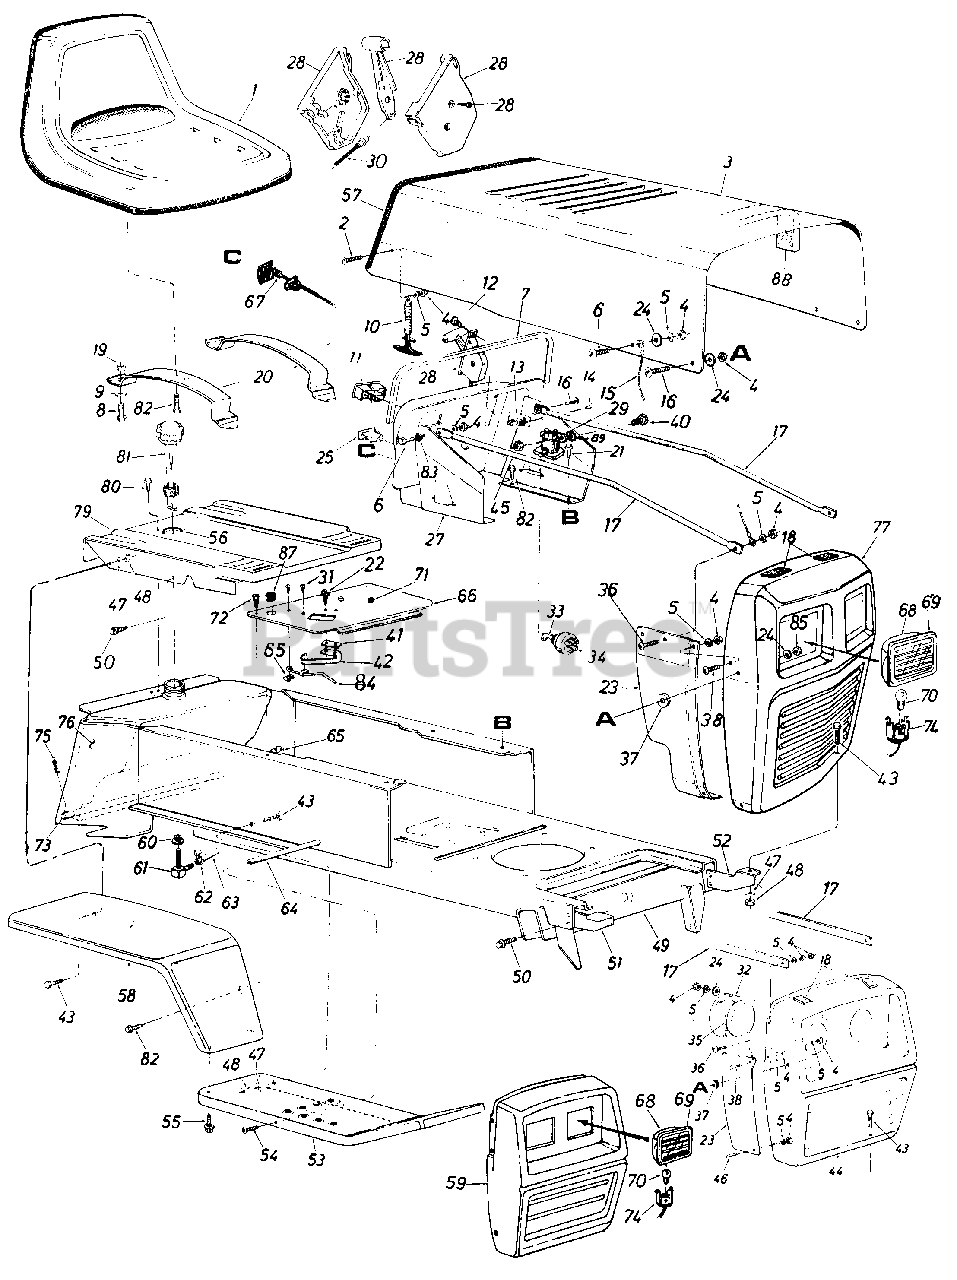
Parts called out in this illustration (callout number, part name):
1	Seat Assembly
2	Truss Mach. Scr. 1/4-20 x .50" Lg.
3	Hood
4	Hex Nut 1/4-20 Thd.
5	L-Wash. 1/4" Scr.'
6	Truss Mach. Scr. 1/4-20 x 1" Lg.
7	Vinyl Molding Strip-29"
8	Hex Nylon Scr. 1/2-13 x .75" Lg.
9	Fl-Wash. .50" I.D. x 1.00" O.D. x .090
10	Hood Latch Ass'y.
11	Ammeter
12	Truss Mach. AB-Tap Scr. #10 x .50" Lg.
13	Circuit Breaker 8 Amp.
14	Hex Tap Scr. #10 x .50" Lg.
15	Hood Stop
16	Truss Mach. Scr. 1/4-20 x .75" Lg.
17	Grille Positioning Rod
18	PVC Foam Strip 1/2 x 1.00 x 2.00" Lg.
19	Hex Nut 1/2-13 Thd.
22	Hex AB-Tap Scr. #8 x .5" Lg.
23	Grille Side Panel-R.H.
24	Fl-Wash. 1/4" I.D.
25	Light Switch
27	Dash Panel Ass'y.
28	Throttle Control Box Comp.
29	Solenoid
30	Throttle Control Cable
31	Truss Hd. Scr. #10 x .50" Lg.
32	Head Lamp Retainer
33	Ignition Key
34	Ignition Switch
35	Head Lamp
36	Truss Machine Scr. 1/4-20 x .75" Lg.
37	Rubber Wash. .50" kD. x 1.00 O.D. x .25 Thk.
38	Truss Mach. Scr. 1/4-20 x .50" Lg.
40	Hex Bolt 1/4-20 x .50" Lg.
41	Insulator Nut Plate
42	Switch Spring
43	Hex Scr. 5/16-18 x .75" Lg.
44	Grille Ass'y. (Painted)
45	Hex Sems Nut 1/4-20 Thd.
46	Truss Mach. Scr. 1/4-20 x .50" Lg.
47	L-Wash. 5/16" Scr.
48	Hex Nut 5/16-18 Thd.
49	Lower Frame Ass'y.
50	Hex Thd. Rolling Scr. 5/16" x .75" Lg.
51	Grille Mount Brkt.-R.H.
52	Grille Mount Brkt.-L.H.
53	Running Board-R.H.
54	Truss Mach. Scr. 5/16-18 x .75" Lg.
55	Hex Thd. Rolling Scr. 5/16-24 x .75" Lg.
56	Grommet
57	Vinyl Moulding Strip-30"
58	Fender Ass'y.-R.H.
59	Grille With Sq. Headlights
60	Bushing
61	90ø Nipple
62	Hose Clamp 3/8"
63	Gas Line 46" Lg.
64	Running Board Rod
65	Speed Nut #10-24 U-Type
66	Transmission Cover Ass'y.
67	Choke Control Comp.
68	Headlight Housing
69	Headlight Lens
70	Lamp
71	Snap Bushing
72	Truss Hd. Scr. #10 x .50"
73	Hitch Rod
74	Headlight Socket
75	Internal Cotter Pin
76	Gas Tank
80	Hex Thd. Rolling Scr. 5/16-24 x .75" Lg.
81	Gas Gauge
82	Hex Thd. Rolling Scr. 5/16-24 x .75" Lg.
83	External Wash. 1/4" I.D.
84	Shift Lever Spring
85	Hex L-Nut 1/4-20 Thd.
87	Plastic Bushing
88	PVC Foam Strip
89	External L-Wash. 1/4" I.D.
